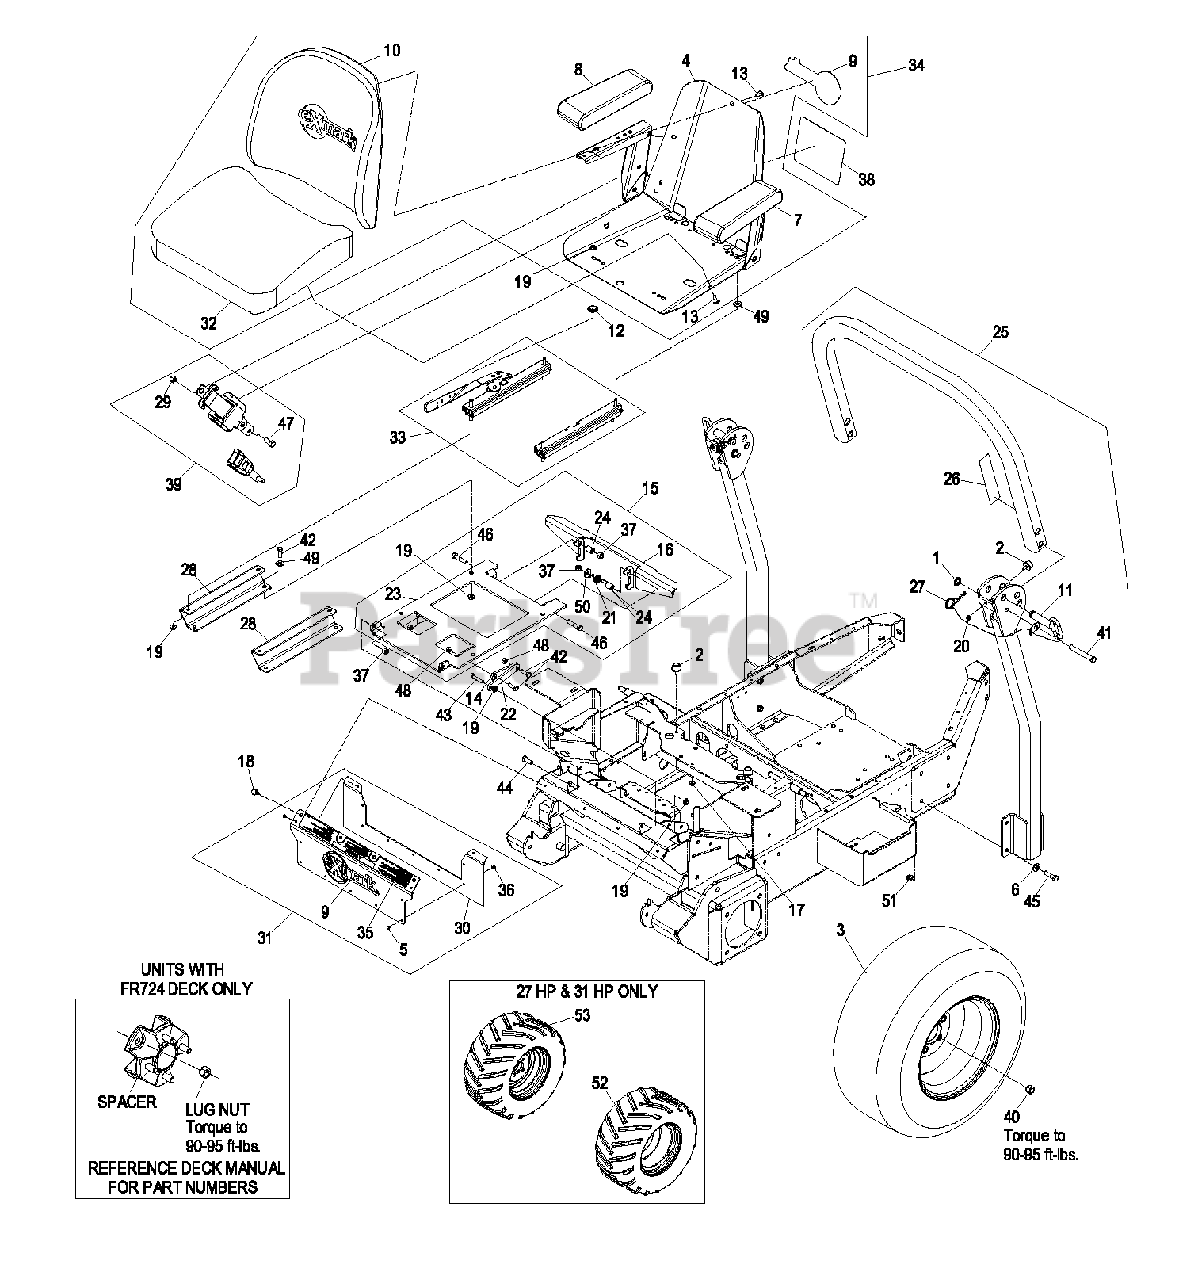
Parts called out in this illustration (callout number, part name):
1	NUT-PUSH
2	BUMPER-RUBBER
3	ASM,WHEEL AND TIRE
4	FRAME-SEAT
5	RIVET-POP
6	WASHER-BELLEVILLE
7	CUSHION,ARMREST LH
8	CUSHION,ARMREST RH
9	DECAL,EXMARK LOGO
10	CUSHION,SEAT BACK
11	PIN-FOLD, ROPS
12	SPACER-TRACK
13	BOLT-SEAT
14	LINK-STOP, SEAT
15	ASM, SEAT FRAME FMZ
18	SCREW-HWH, THREAD CUT
20	NUT-LOCK, NI
22	LINK,FMZ LWR SEAT STOP (P
23	ASM, SEAT FRAME FMZ
24	BUSHING-LEVER, LIFT
25	KIT,ROPS FMZ
26	DECAL-WARNING, FOLDING RO
27	HAIRPIN
28	SUPPORT, ANGLED SEAT
29	NUT-LOCK
30	Skirt, Rubber
31	ASM,FRONT CONSOLE W/ DECA
35	DECAL,TOP CONSOLE
36	WASHER-FLAT
37	NUT-LOCK, NI
38	DECAL,FR SERVICE AID
40	NUT-LUG
41	PIN-CLEVIS
42	SCREW-HH
43	SCREW-HH
44	SCREW-HH
45	SCREW-HH
46	SCREW-HH
47	SCREW-HH
48	NUT-LOCK, NI
49	WASHER-FLAT
50	WASHER-FLAT
51	NUT-HHF, WHIZ
52	ASM,WHEEL AND TIRE LUG LH
52	TIRE (24X12-12) 4-PLY LUG
53	ASM,WHEEL AND TIRE LUG RH
53	TIRE (24X12-12) 4-PLY LUG
